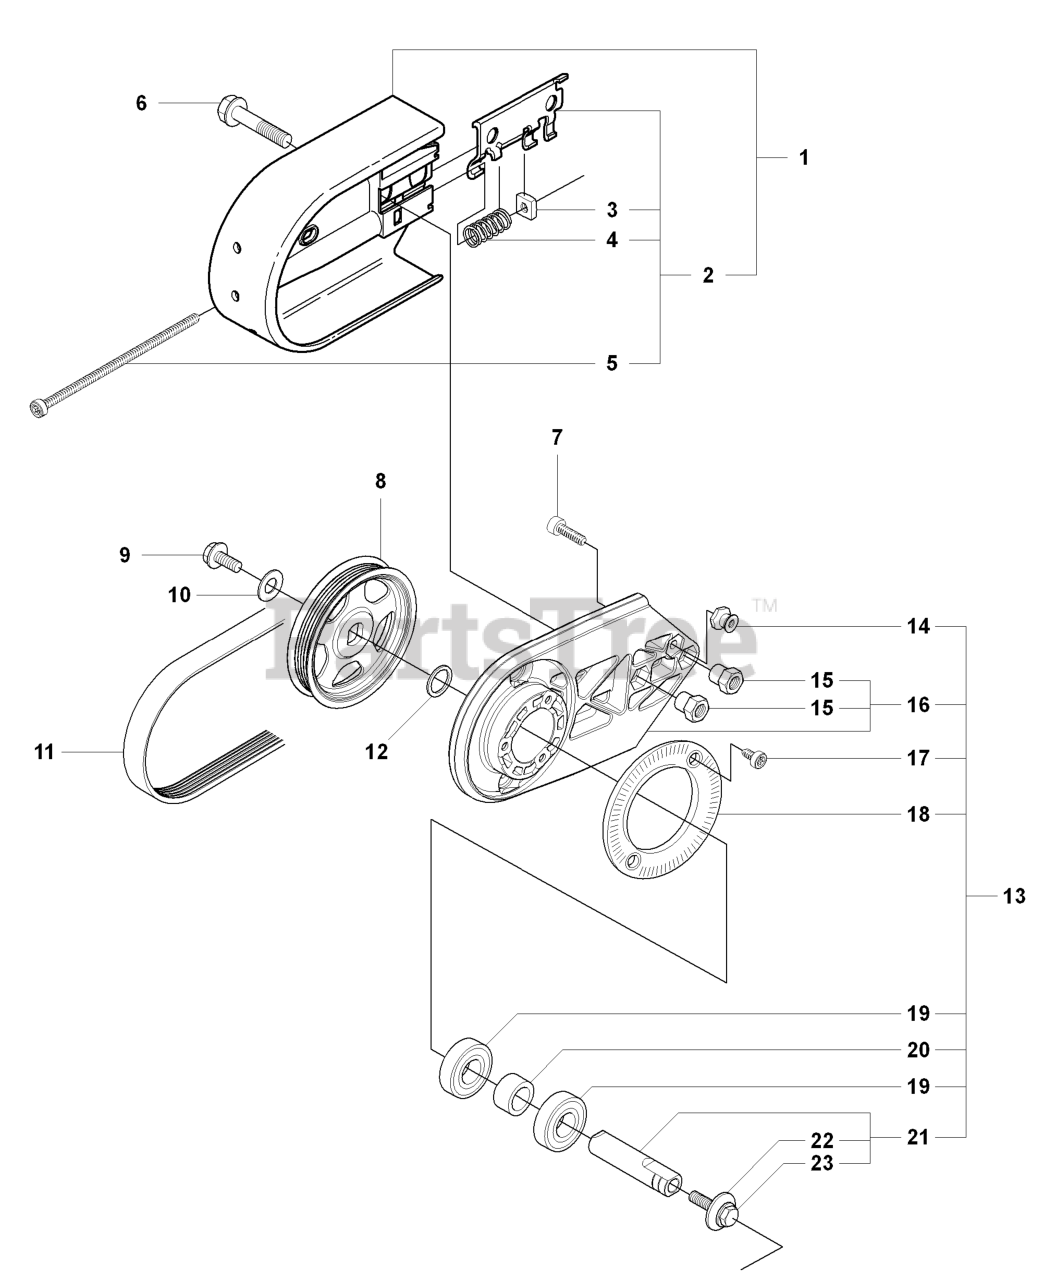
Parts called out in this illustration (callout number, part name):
1	BELT GUARD
2	TENSIONER
5	SCREW
6	BOLT
7	SCREW MC6S 5X16
8	%PULLEY
12	WASHER 15X21
13	HOUSING
16	HOUSING
19	BALL BEARING
21	SHAFT
22	WASHER
23	SCREW
